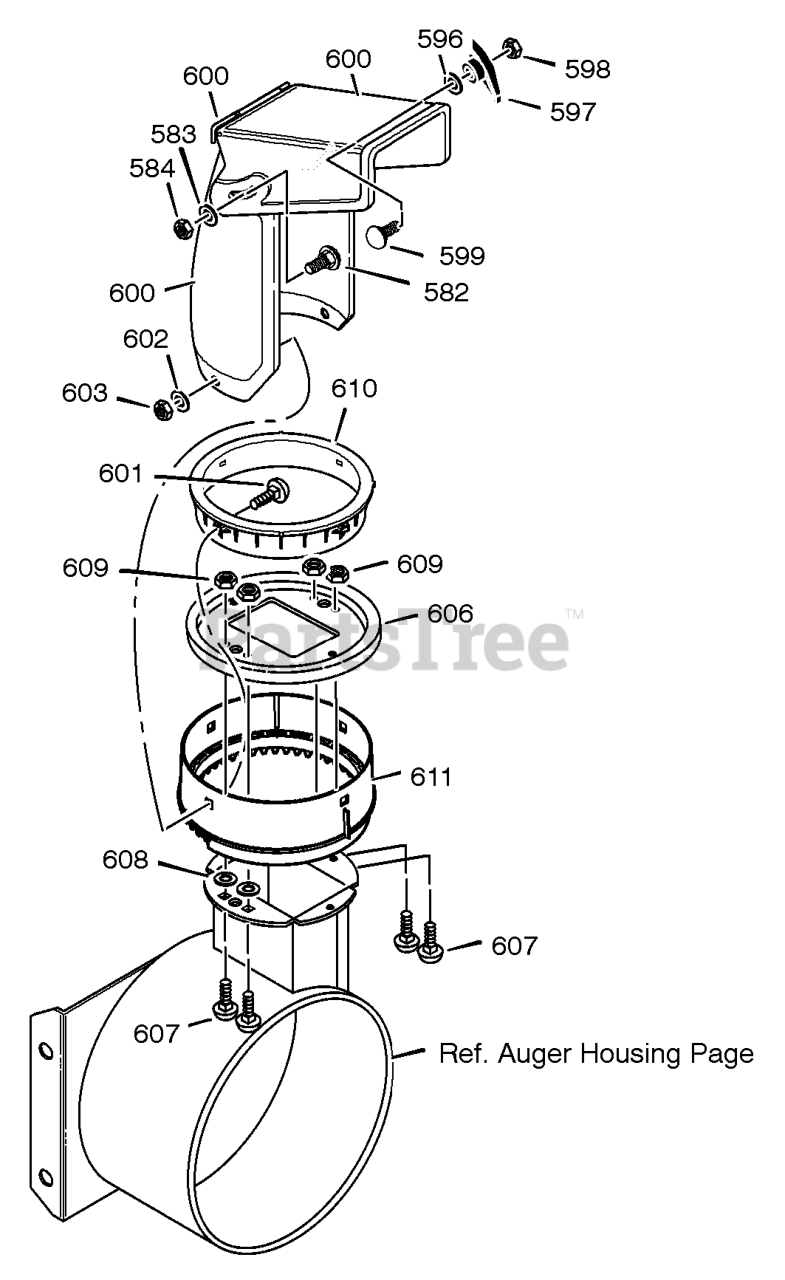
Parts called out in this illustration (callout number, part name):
582	SCREW, 5/16-18 x 0.75
583	WASHER, FLAT
584	NUT, 5/16-18 REGHEXCTRLK
596	WASHER
597	KNOB, T 3.00
598	NUT, 5/16-18 REGHEX
599	BOLT, 5/16-18X1.125
600	CHUTE ASSEMBLY
601	BOLT, 5/16-18 X1.00
602	WASHER, FLAT
603	NUT, 5/16-18 HEXNYL
606	CHUTE COLLAR
607	SCREW, 1/4-20 X 1.00
608	WASHER, FLAT
609	NUT, 1/4-20 HEX NYLOCK
610	RETAINER RING INNER
611	RETAINER RING OUTER
